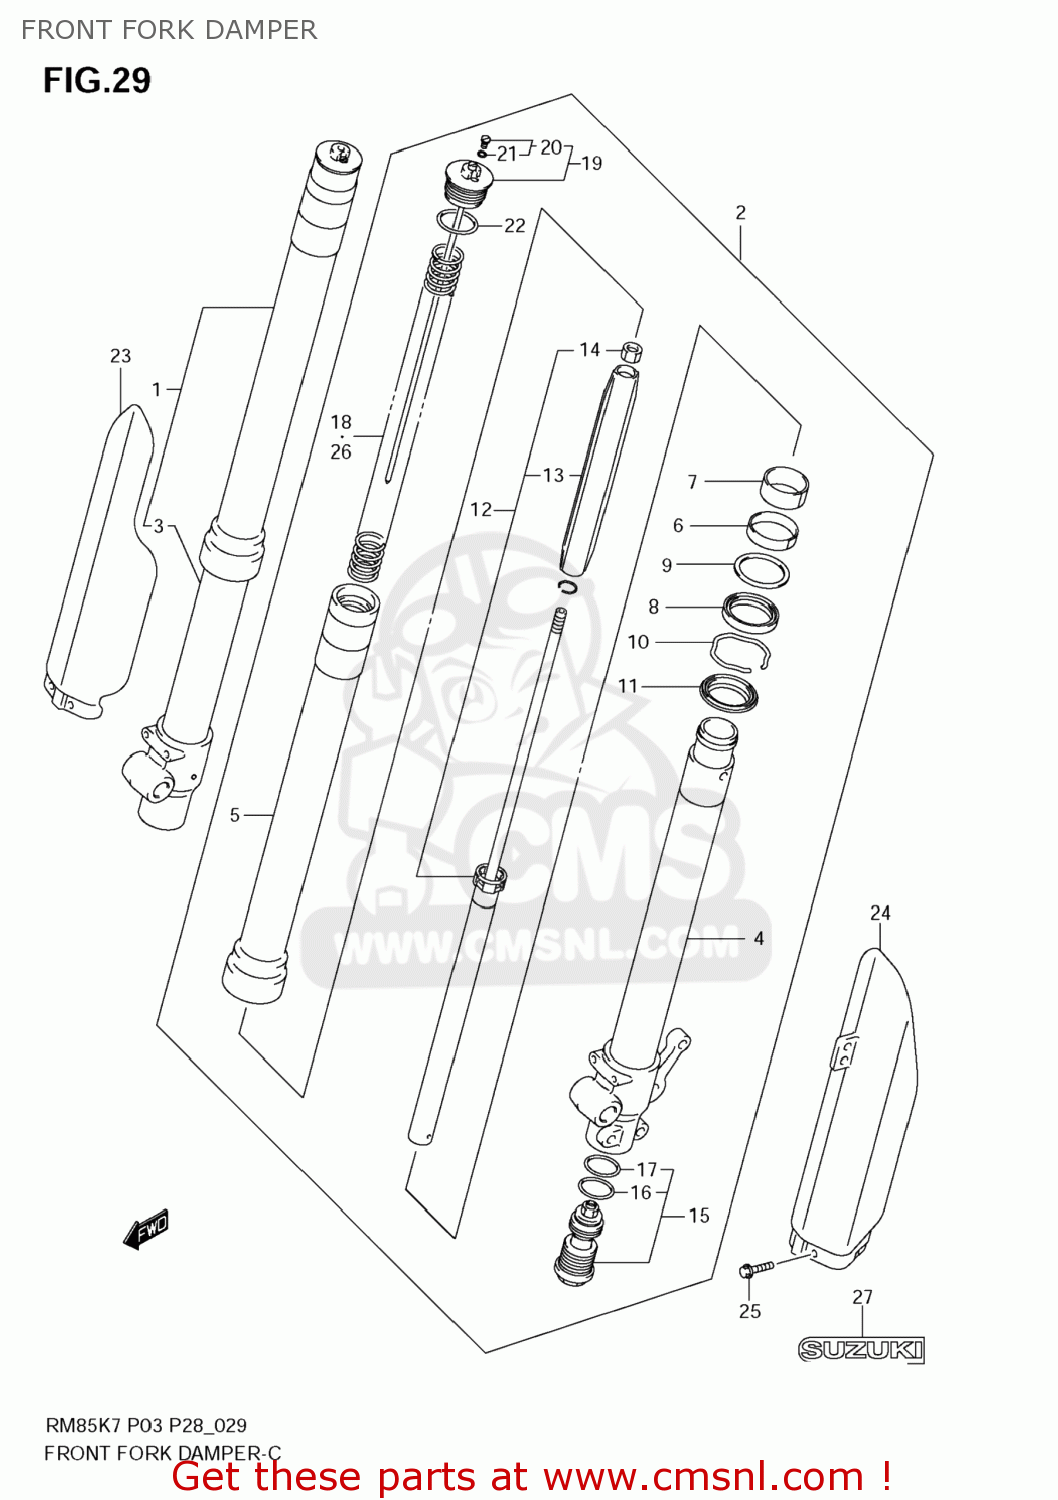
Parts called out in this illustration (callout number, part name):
1	DAMPER ASSY,FR FORK,R
2	DAMPER ASSY,FR FORK,L
3	TUBE,INNER,R
4	TUBE,INNER,L
5	TUBE,OUTER
6	BUSH,GUIDE
7	BUSH,SLIDE
8	OIL SEAL,FRONT FORK
9	SPACER,SEAL
10	RING,STOPPER
11	SEAL,DUST
12	CYLINDER
13	GUIDE,SPRING
14	NUT
15	BOLT,CTR
16	O RING
17	O RING
18	SPRING,FR(K=0.28)
19	BOLT,FORK
20	BOLT,PLUG
21	O RING
22	O RING
23	PROTECTOR,FR FORK,R
24	PROTECTOR,FR FORK,L
25	BOLT(6X10)
26	SPRING,FR(K=0.26)
27	EMBLEM,SUZUKI
